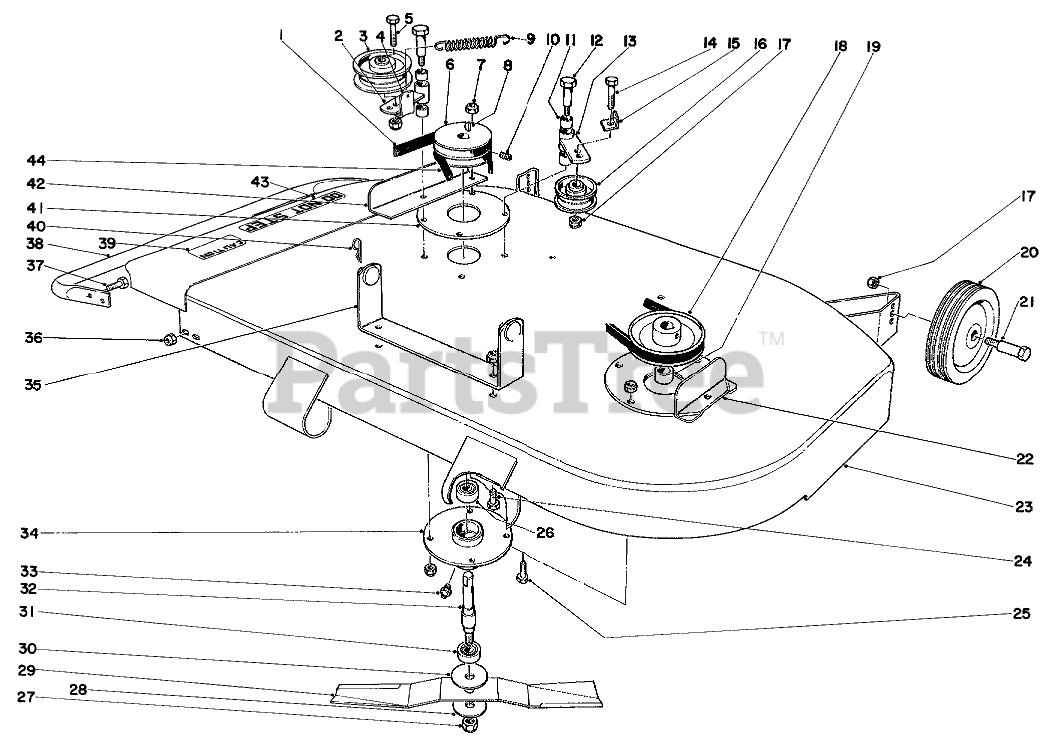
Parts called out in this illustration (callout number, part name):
1	Belt
2	Idler Plate Incl. Ref. #11
3	Idler Pulley
4	belt Retainer
5	SCREW-HH
6	BLD SPDLE PULLEY (MACH)
7	NUT-LOCK, CONE
8	KEY-WOODRUFF
9	Spring Tension
10	SCREW-SET, HSH
11	BUSHING
12	SHOULDER BOLT
13	Idler Plate
14	SCREW-HH
16	PULLEY-IDLER
17	NUT-LOCK, CONE
18	Pulley
19	Spacer
20	Wheel
22	Belt Guard
23	Housing
24	SCREW-HH
25	SCREW-HH
26	Bearing
27	NUT-LOCK, CONE
28	WASHER
29	Blade
30	WASHER
31	.6693 RP BALL BEARING
32	Blade Spindle
33	FITTING-GREASE
34	Spindle Housing
35	Height Adjustment Bracket
36	NUT-LOCK, CONE
37	SCREW-HH
38	Blade Guard
39	Decal
40	PIN-COTTER
41	Washer
42	Guard
43	Decal
